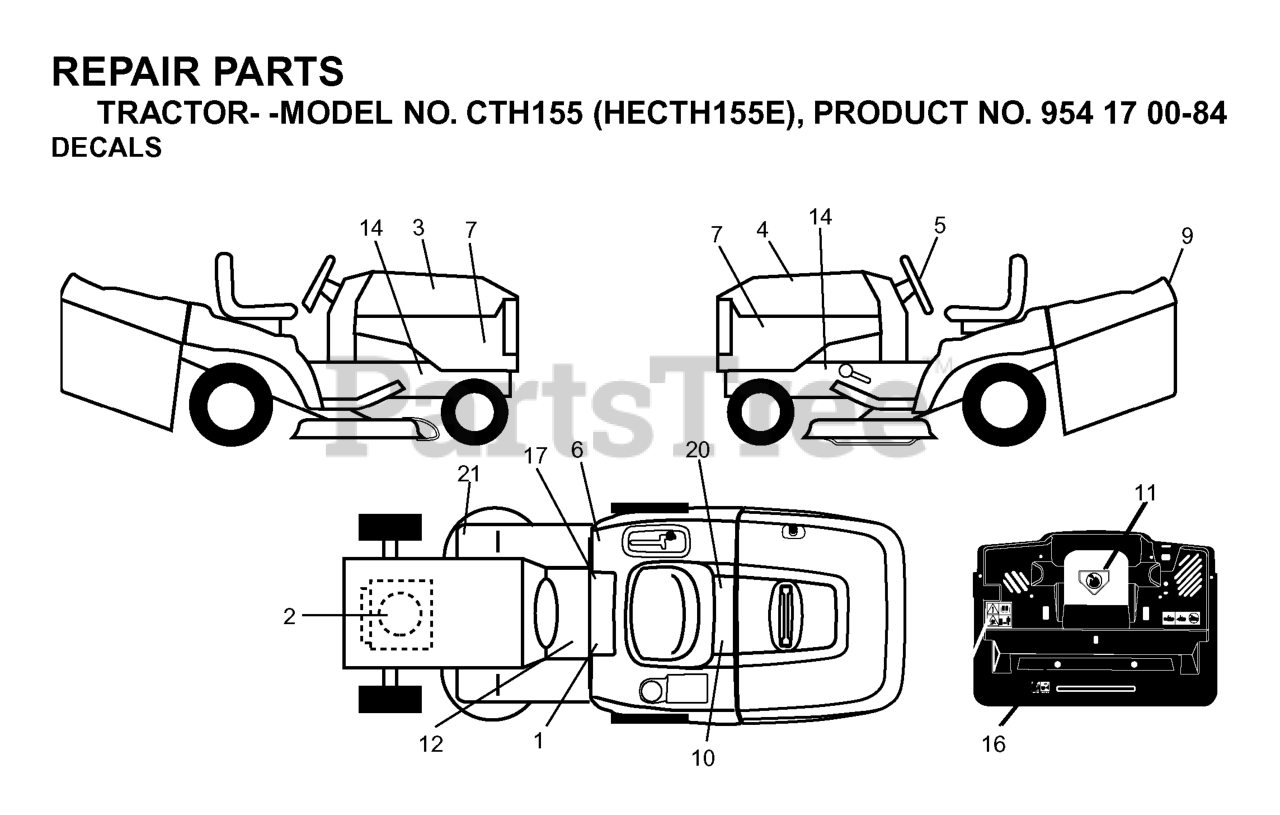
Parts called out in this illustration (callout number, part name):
1	DECAL READ OWNER'S MAN SYMS
5	DECAL.WHEEL.STEERING.HUSQ.PERM
6	Decal, Fender 100 DB/CE
7	DECAL PNL SIDE
9	DECAL FENDER HUSQ
10	DECAL BTRY SYMBOLS
11	DECAL.INTERNATIONL.CUTFINGER
12	DECAL
16	DECAL
17	DECAL PARK BRAKE
20	DECAL.BYPASS.FENDER.CRD.LT.YT
